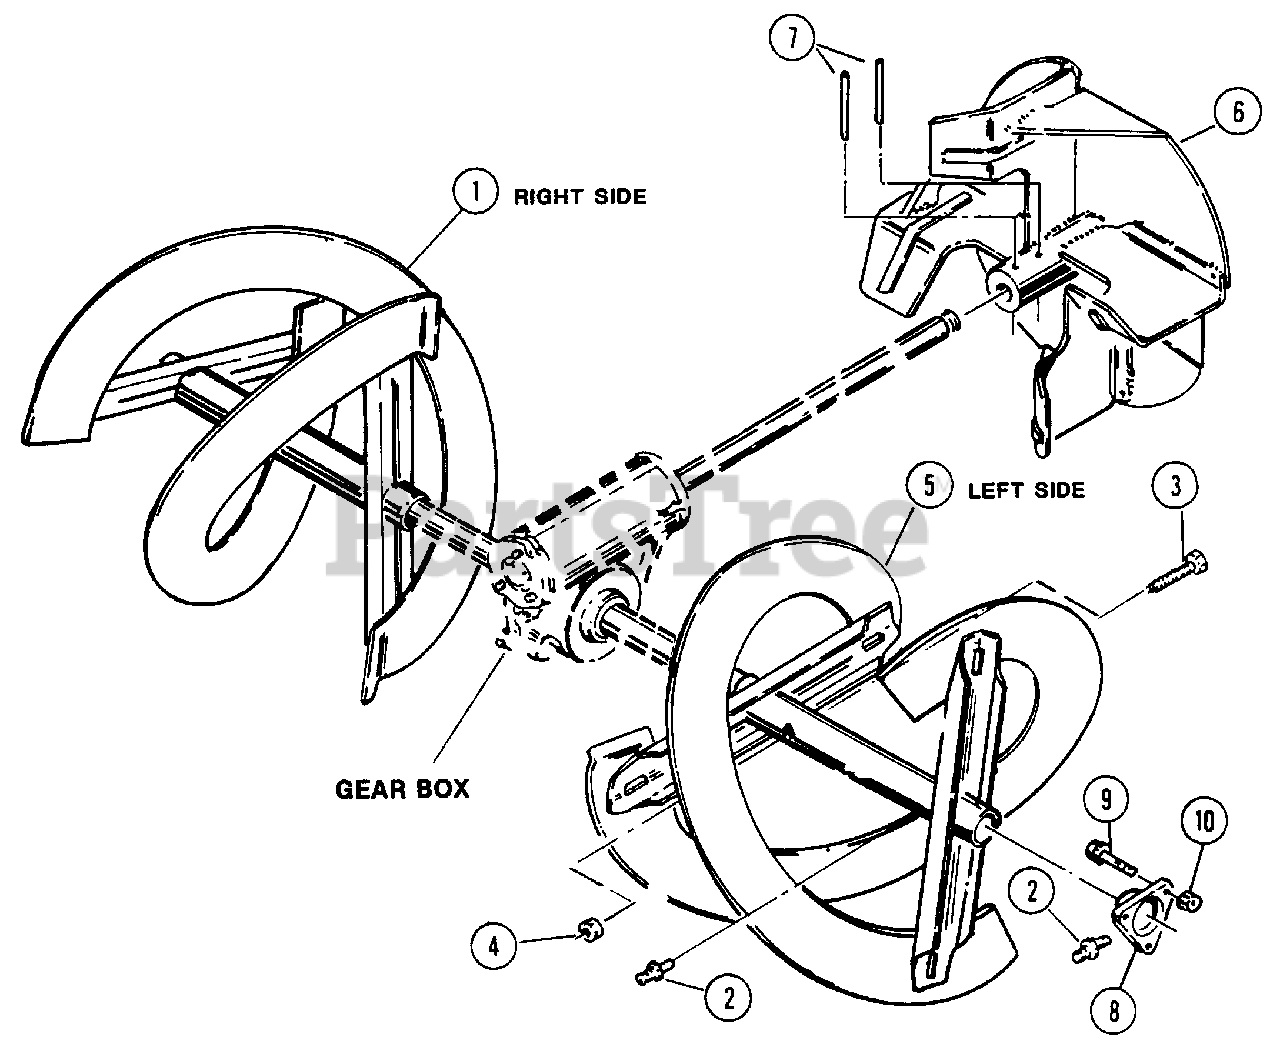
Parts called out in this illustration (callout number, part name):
1	AUGER, Right Side
2	LUBE FITTING, Straight (press-fit for .187 dia. Hole)
3	BOLT, 5/16-18 x 1-7/8" Shear
4	LOCKNUT, Hex Flange
5	AUGER, Left Side
6	FAN, Impeller
7	PIN, 1/4 x 1-1/2" Roll
8	BEARING, Auger Shaft
9	BOLT, 1/4cx5/8 Hex Flange Lock
10	NUT, 1/4C Hex Flange
